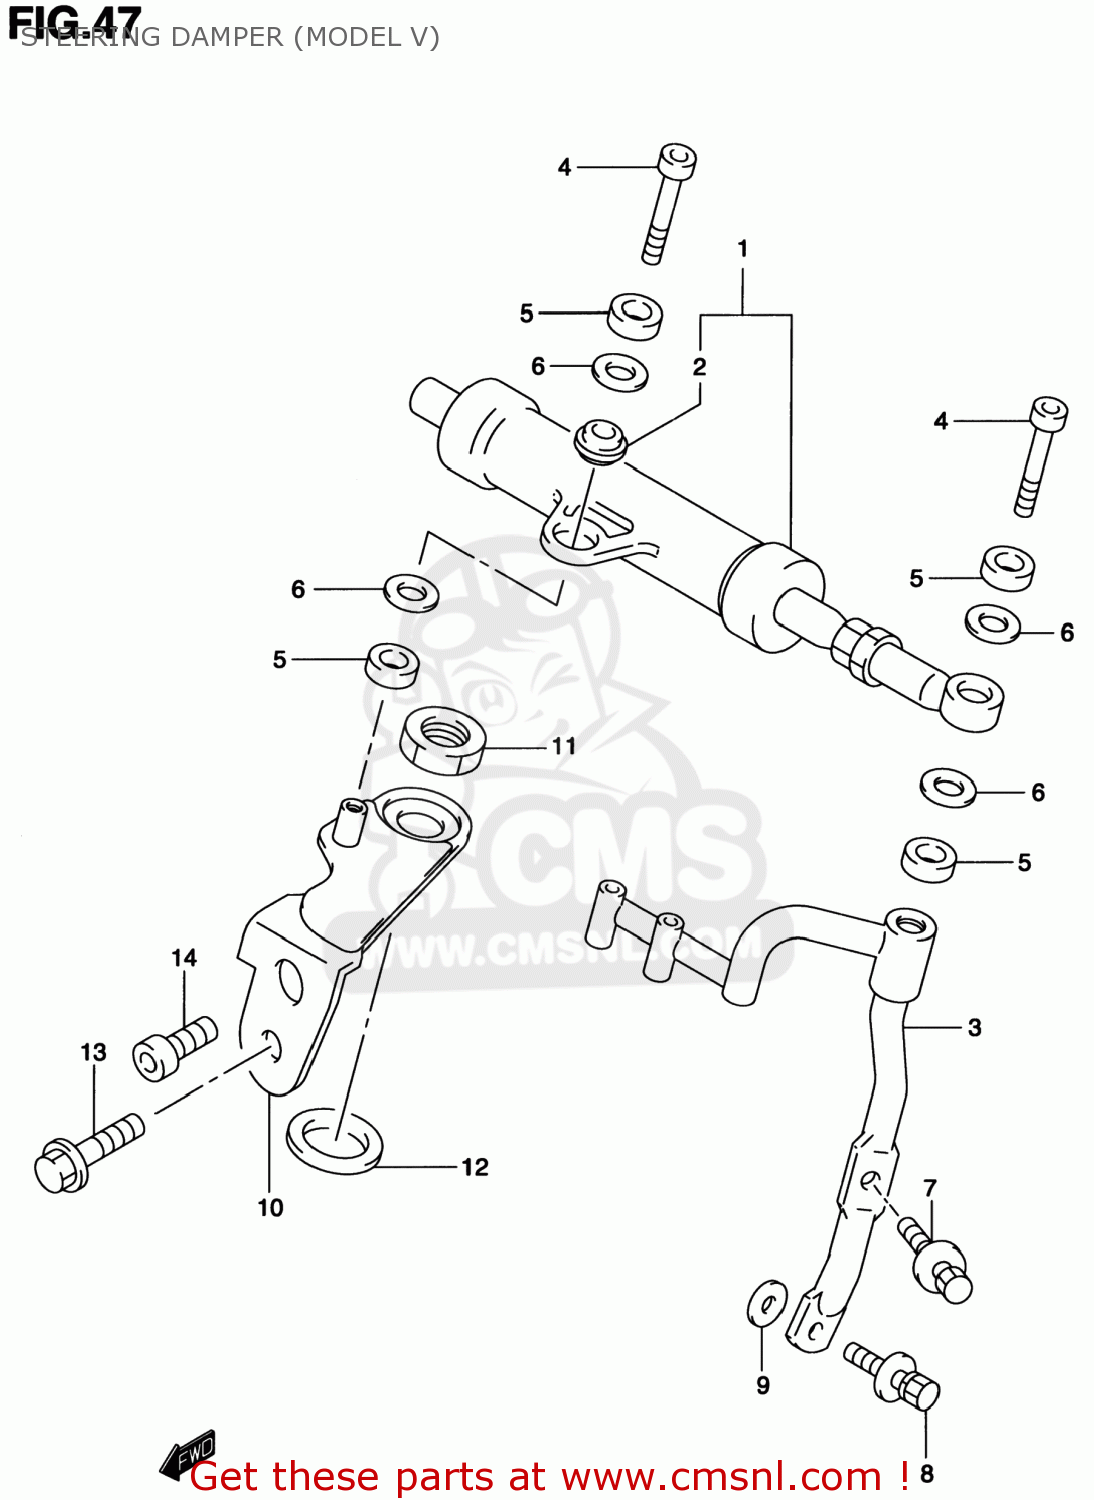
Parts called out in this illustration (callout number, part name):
1	DAMPER ASSY,STEERING
2	BEARING(8X17.5X11)
3	STAY,STEERING DAMPER
4	BOLT(8X35)
5	6
6	SHIM(8X12X0.8)
7	BOLT(6X30)
8	BOLT,STAY,LOWER 6X35
9	WASHER(6.5X20X1.6)
10	PLATE,STEERING DAMPER
11	NUT,STEM TOP
12	WASHER,STEERING DAMPER
13	BOLT
14	BOLT(8X32)
